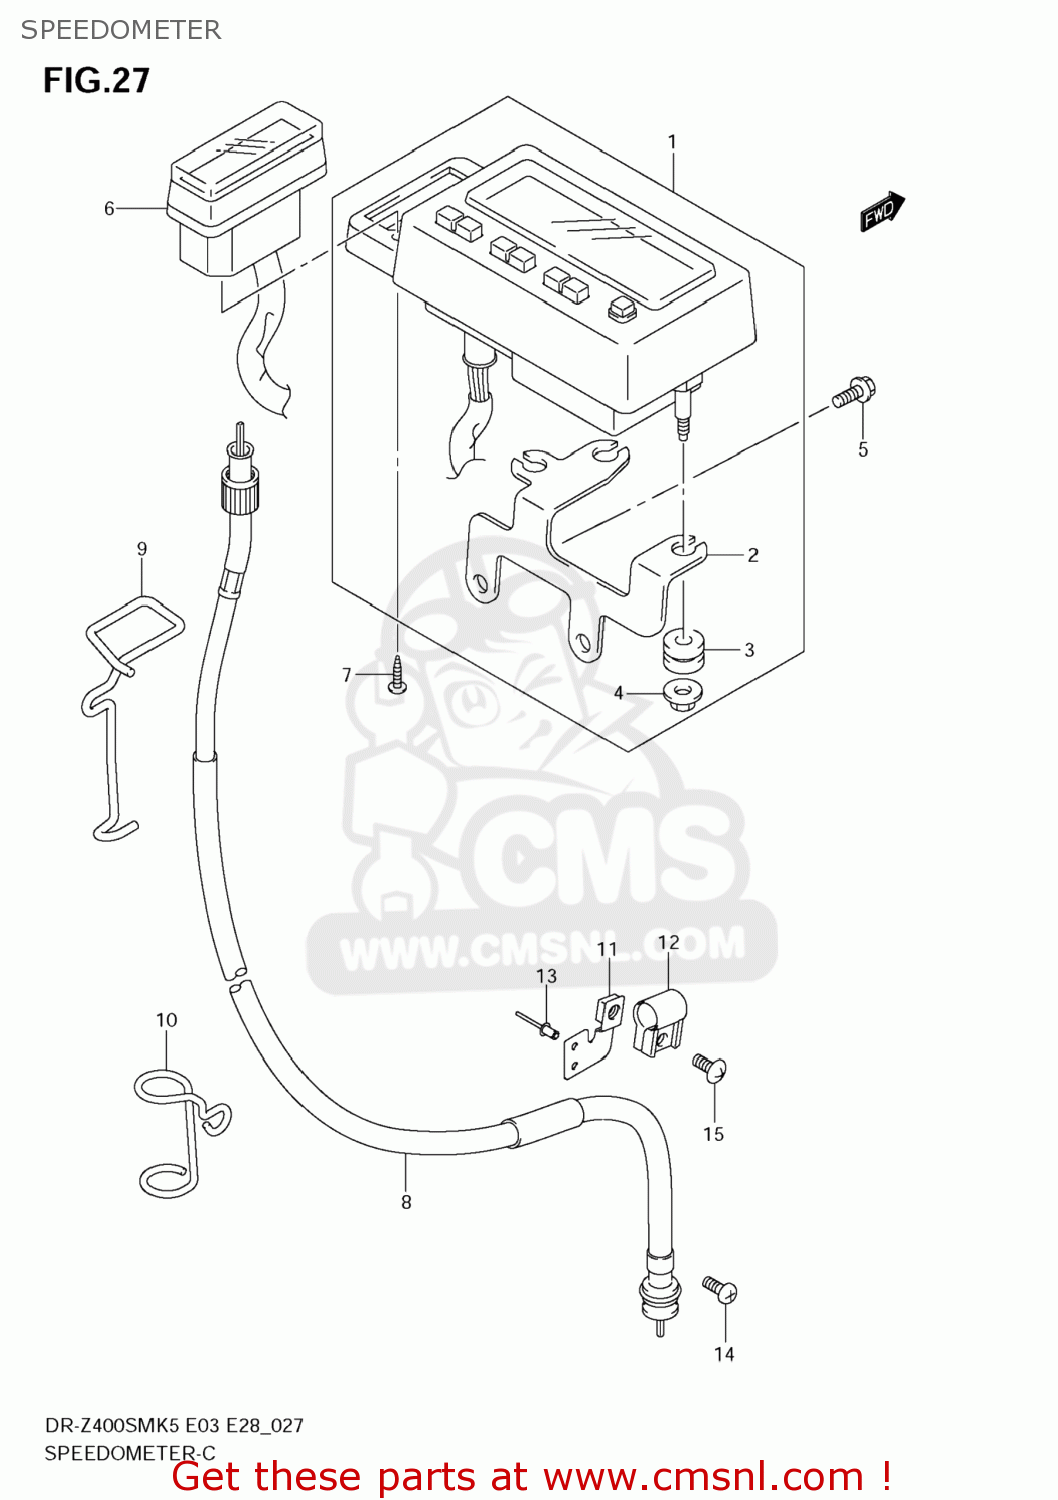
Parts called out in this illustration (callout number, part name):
1	SPEEDOMETER ASSY
2	BRACKET
3	CUSHION,METER
4	NUT
5	BOLT
6	BOX ASSY,PILOT LAMP
7	SCREW
8	CABLE ASSY,SPEEDOMETER
9	GUIDE,SPEEDOMETER CABLE NO.3
10	GUIDE,METER CABLE NO.1
11	GUIDE,METER CABLE NO.2
12	CLAMP,BRAKE HOSE
13	RIVET
14	SCREW
15	SCREW
